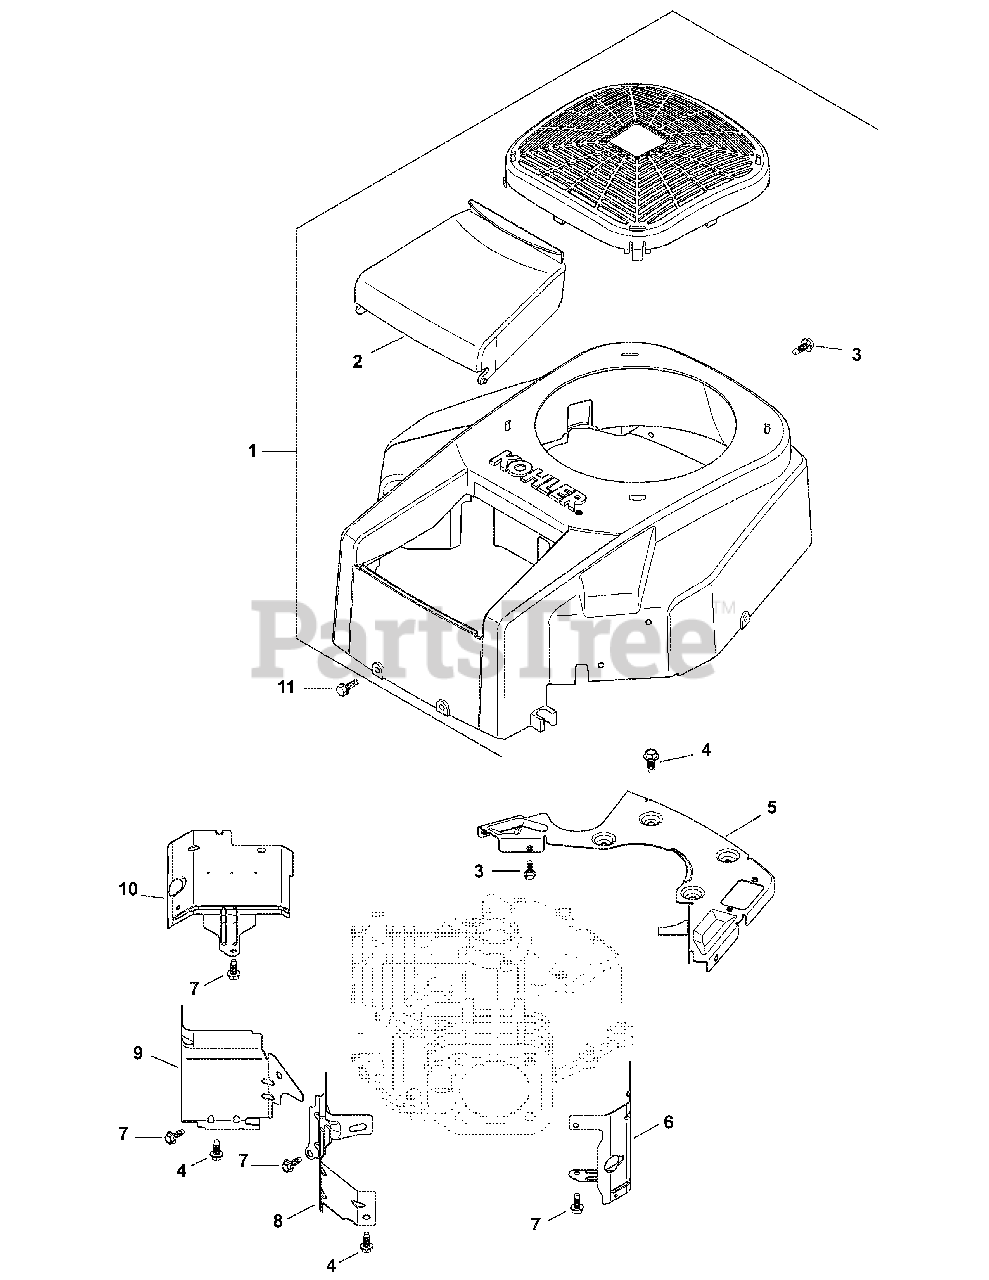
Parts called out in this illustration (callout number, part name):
1	Kit, Blower Housing-Fixed Guard (Includes 2 & KH-41 037 10-S)
2	Cover, Air Cleaner (Black)
3	Screw, FLG THD FRM M5 x .8 x 10
4	Screw, FLG THD FRM M5 x .8 x 16
5	Kit, Backing Plate
6	Baffle, Cyl Barrel-#2 Side
7	Screw, FLG THD FRM M6 x 1.0 x 16
8	Baffle, Valley #2 Side
9	Baffle, Valley #1 Side
10	Baffle, CYL Barrel - #1 Side
11	Screw, Tap M6 x 1.7 x 18
